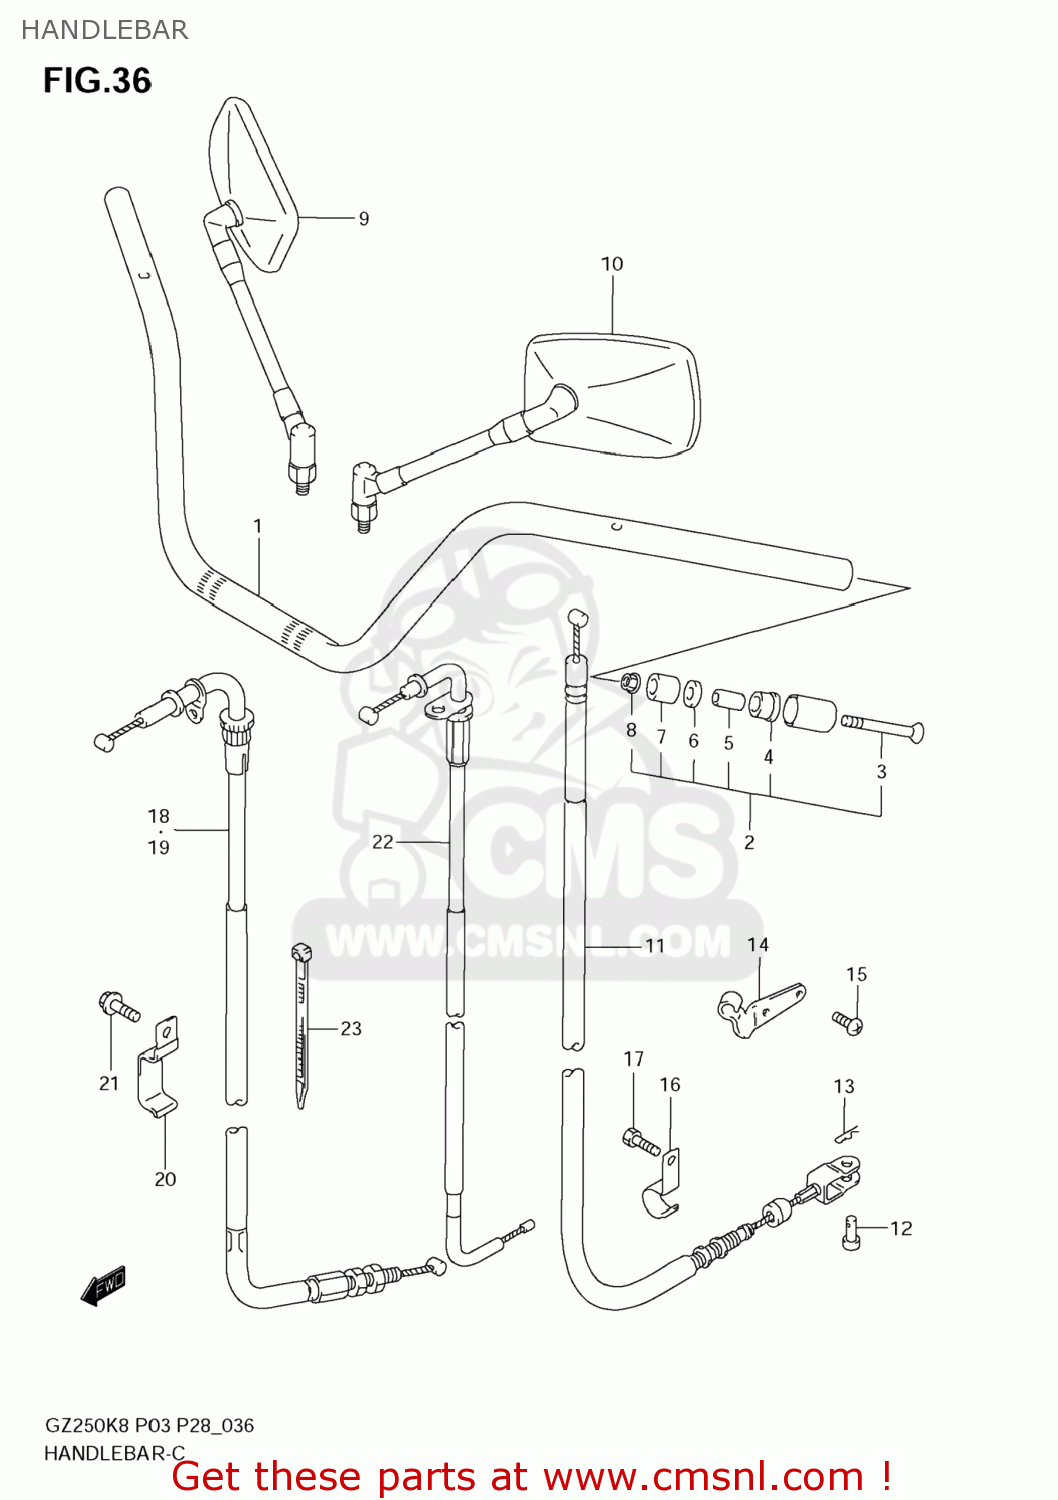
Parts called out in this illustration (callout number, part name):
1	HANDLEBAR
2	BALANCER SET,HANDLEBAR
3	SCREW(6X125)
4	EXPANDER,HANDLE BALANCER NO.2
5	SPACER,EXPANDER
6	WASHER(6.5X14X2)
7	EXPANDER,HANDLE BALANCER
8	NUT
9	REARVIEW MIRRO
10	REARVIEW MIRRO
11	CABLE ASSY,CLUTCH
12	PIN(L:13)
13	PIN
14	STOPPER,CLUTCH CABLE
15	BOLT
16	CLAMP,CLUTCH CABLE NO.1
17	SCREW
18	CABLE ASSY,THROTTLE NO.1
19	CABLE ASSY,THROTTLE NO.2
20	CLAMP
21	BOLT
22	CABLE,STARTER
23	CLAMP(L:95)
